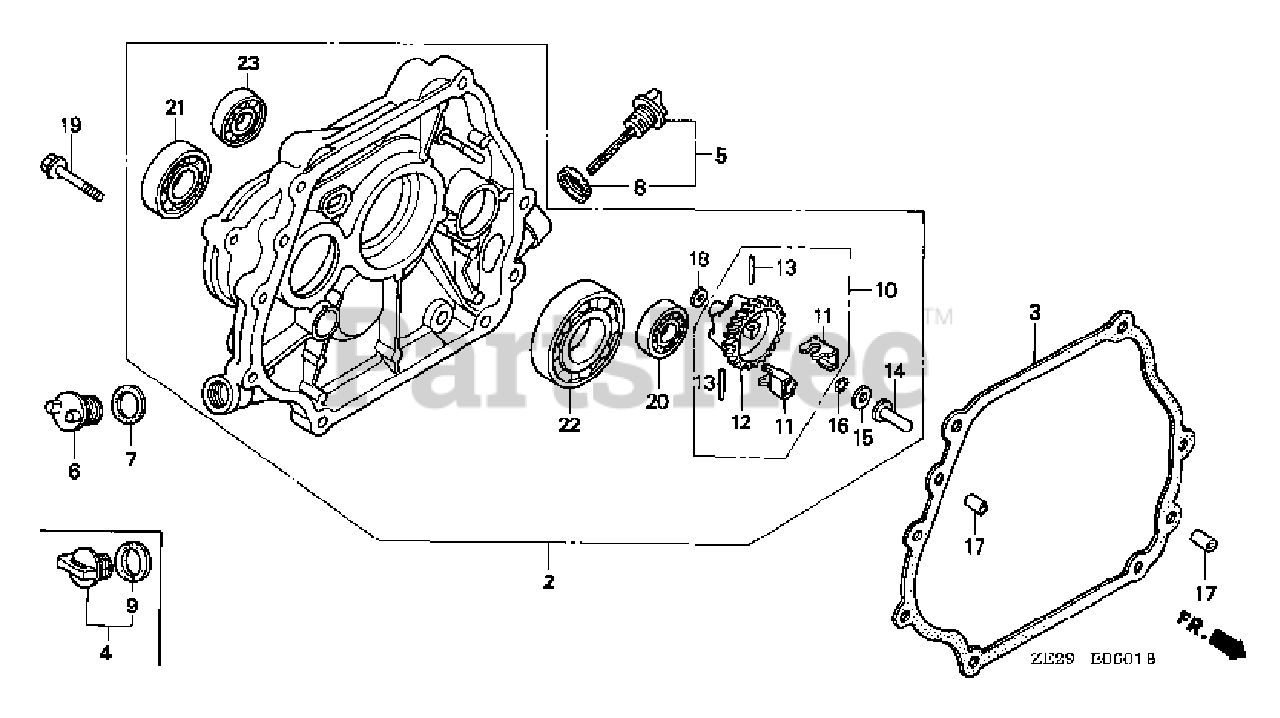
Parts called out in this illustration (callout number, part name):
2	COVER ASSY., CRANKCASE (L-TYPE)
3	GASKET, CASE COVER
4	CAP ASSY., OIL FILLER
5	CAP ASSY., OIL FILLER
6	CAP, OIL FILLER
7	GASKET, OIL FILLER CAP
8	GASKET, OIL FILLER CAP
9	GASKET, OIL FILLER CAP
10	GOVERNOR ASSY. (STD)
11	WEIGHT, GOVERNOR
12	HOLDER, GOVERNOR WEIGHT
13	PIN, GOVERNOR WEIGHT
14	SLIDER, GOVERNOR
15	WASHER (6X16)
16	CLIP, GOVERNOR HOLDER
17	PIN, DOWEL (8X12)
18	WASHER, PLAIN (6MM)
19	BOLT, FLANGE (8X35)
21	BEARING, RADIAL BALL (6204)
22	BEARING, RADIAL BALL (6206)
